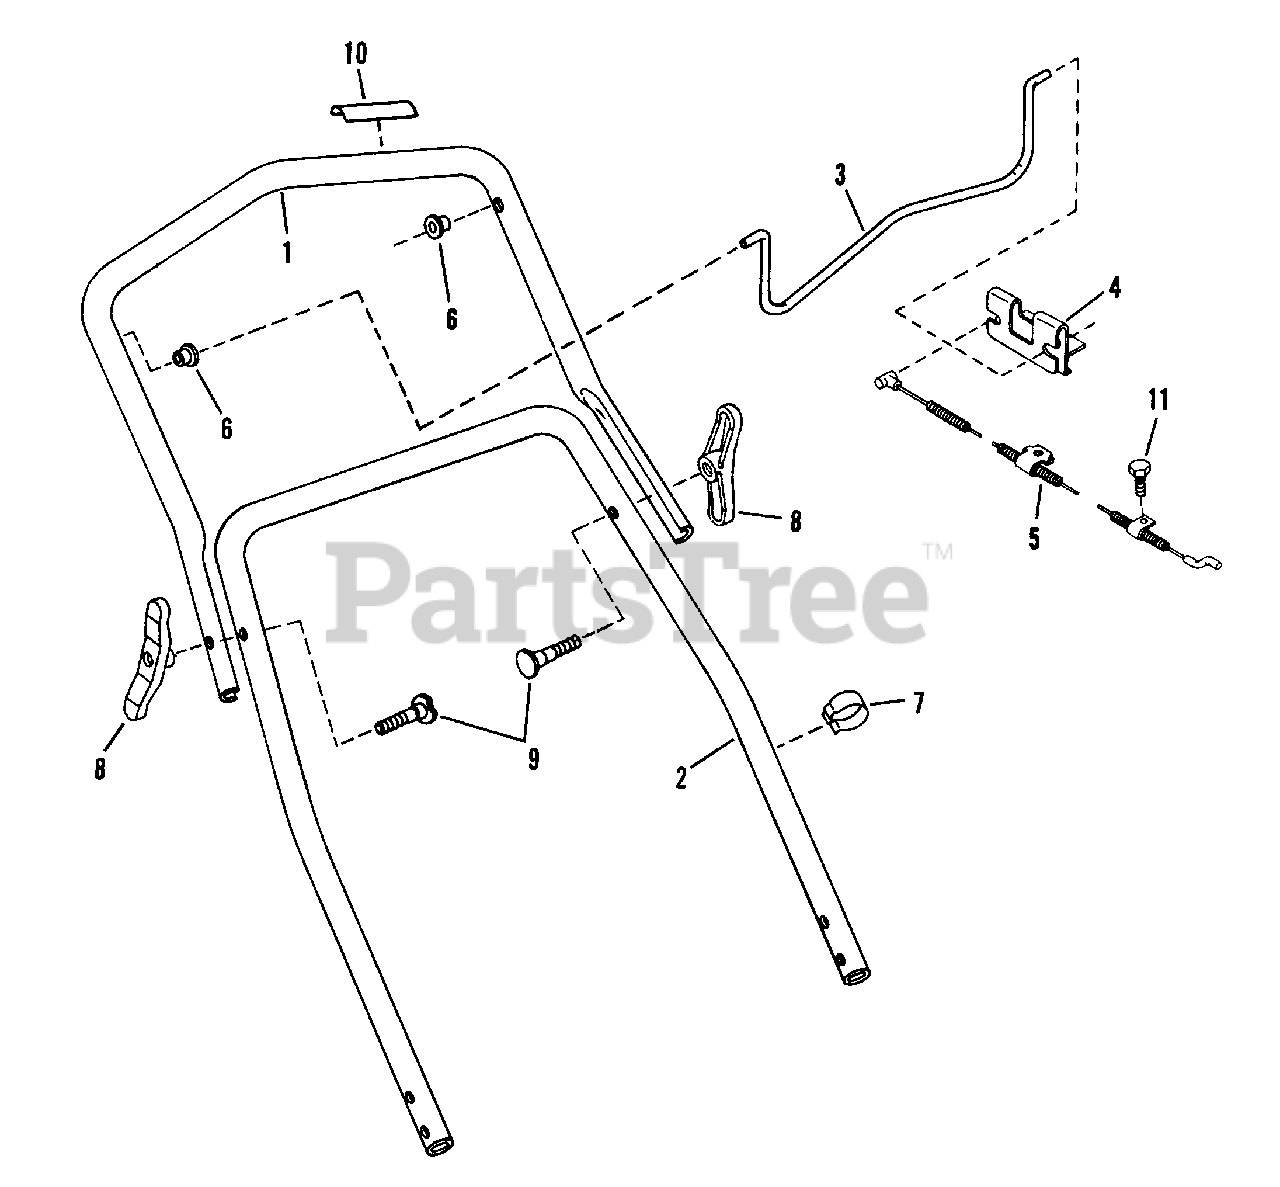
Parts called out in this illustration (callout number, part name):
1	HANDLE, Upper
2	HANDLE, Middle
3	CONTROL, Blade
4	CLIP (Left Hand-Tecumseh, Right Hand-Briggs)
5	CABLE, Control (Briggs & Stratton)
6	BUSHING
7	CLIP
8	NUT, 1/4-20 Wing
9	SCREW, 1/4-20x1-3/8" Curved Head
10	DECAL, Blade Control
11	SCREW, #10-32x1/4" Hex Sems (Tec.)
